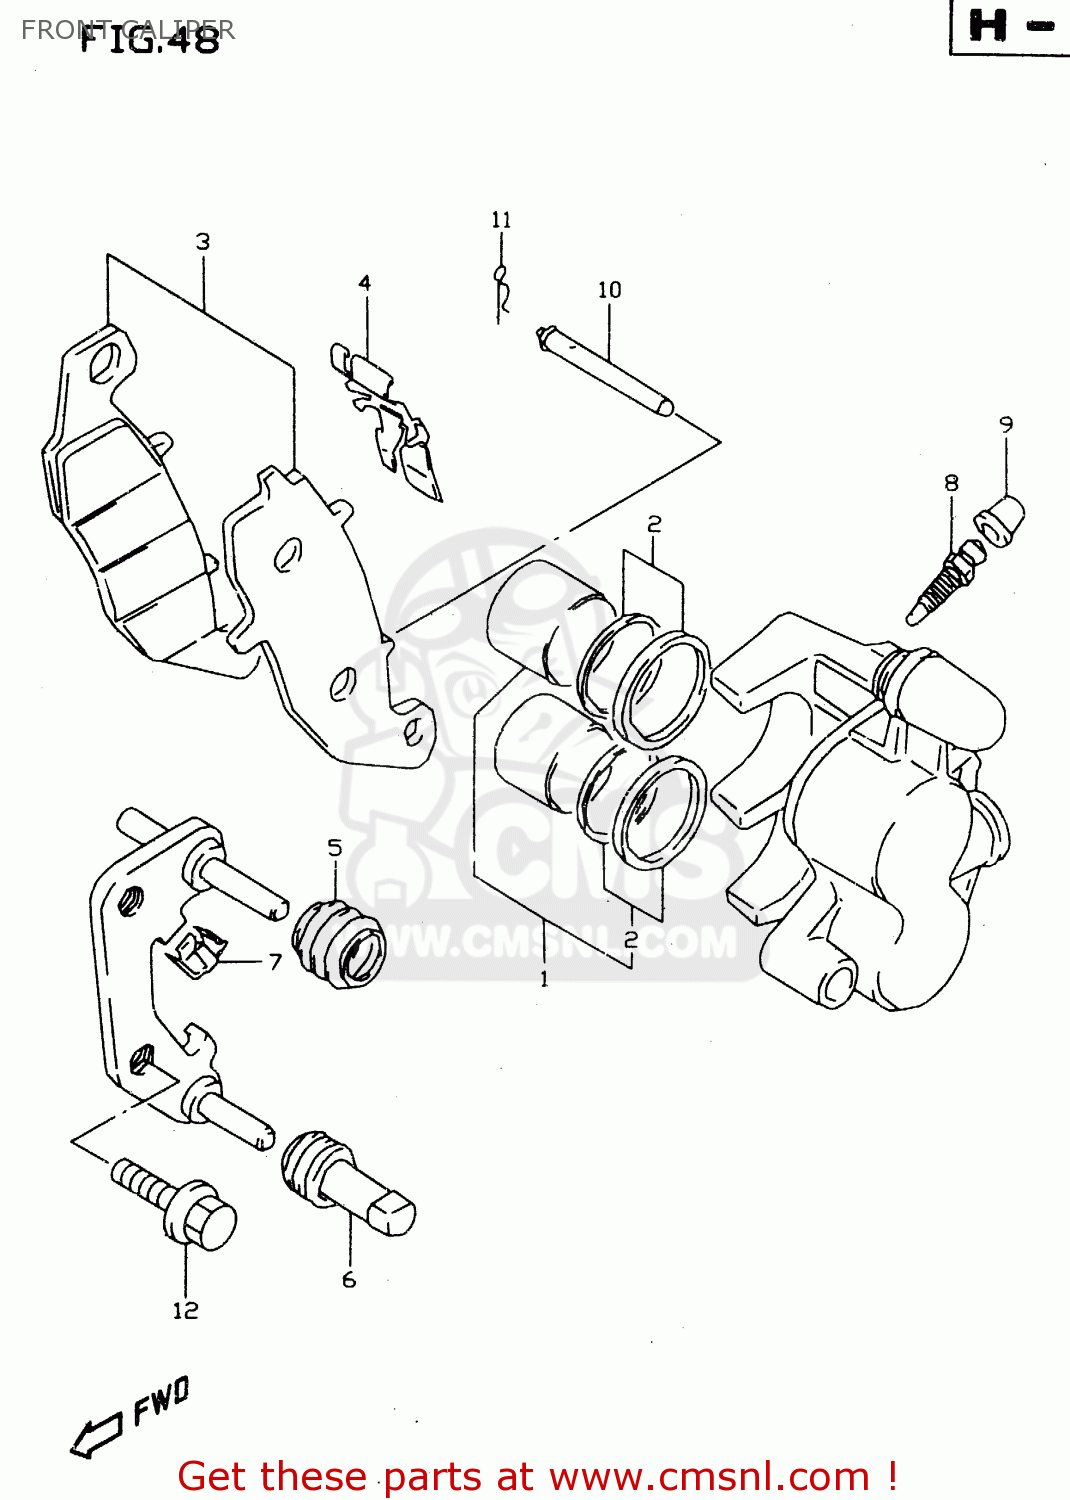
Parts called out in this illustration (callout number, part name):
1	PISTON SET
2	SEAL SET,PISTON
3	PAD SET,R (NAS)
4	SPRING,PAD,R
5	BOOT,AXLE
6	INSULATOR,AXLE
7	GUIDE,PAD
8	BLEEDER
9	CAP,BLEEDER PLUG
10	PIN,PAD
11	CLIP,PAD PIN
12	BOLT
